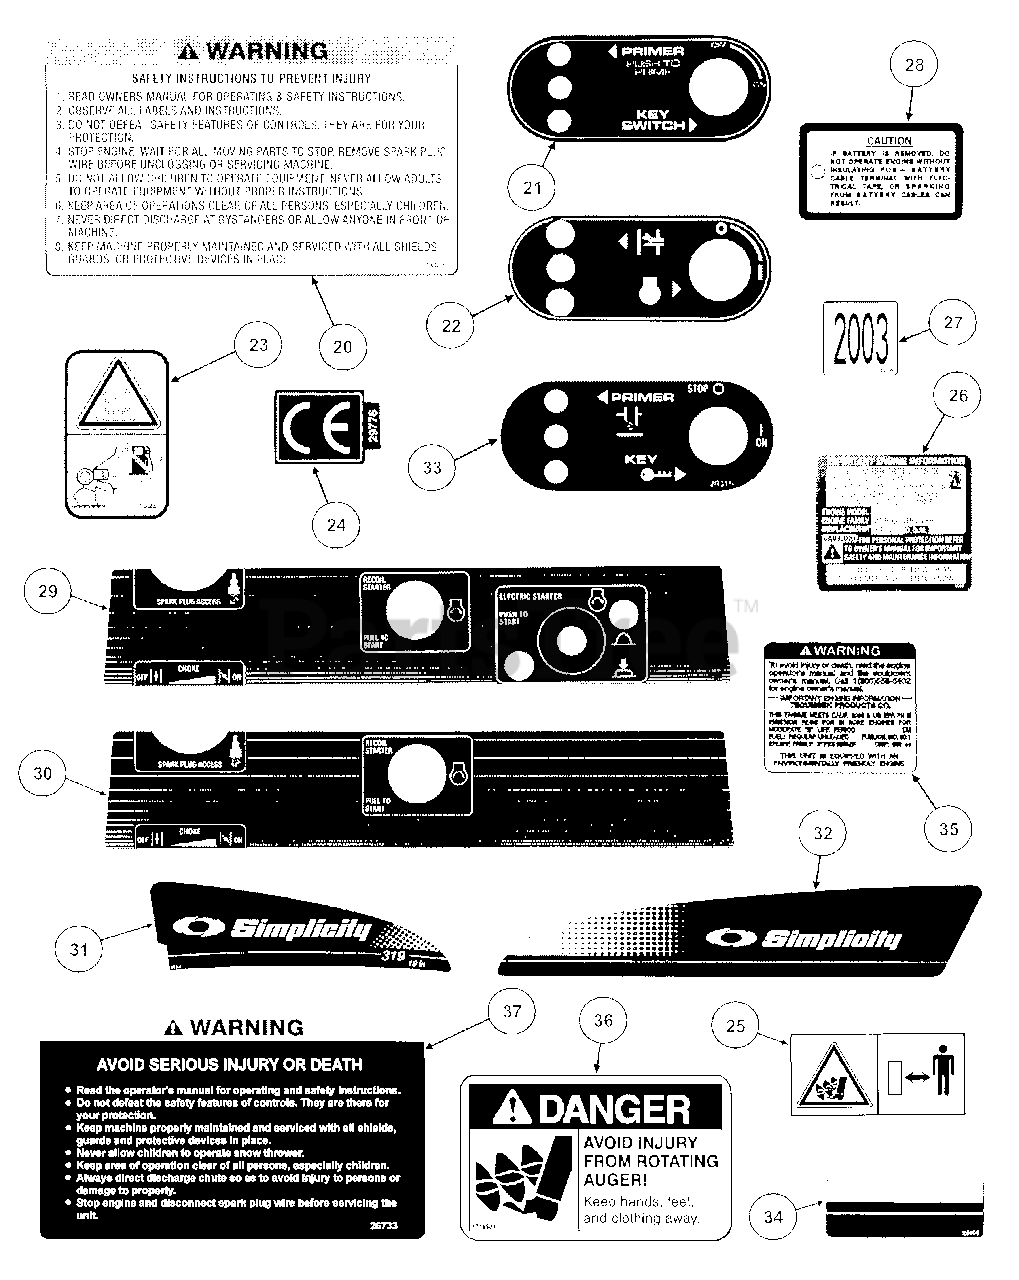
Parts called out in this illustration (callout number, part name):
20	DECAL, Warning Safety Instructions
21	DECAL, Primer Instruction
22	DECAL, Primer Instruction
23	DECAL, Fuel Safety
24	DECAL, Euro Community
25	DECAL, Foot/Danger
26	DECAL, Tecumseh 3HP Carb/EPA Certified
27	DECAL, 2003 Year of Manufacture
28	DECAL, Caution Tag
29	DECAL, Panel Instructions
30	DECAL, Panel Instructions
31	DECAL, Top Cover, Left Hand
32	DECAL, Top Cover, Right Hand
33	DECAL, Primer Instruction/Key Switch
34	DECAL, Top Cover, Front
35	DECAL, Tecumseh 3HP Carb/EPA Certified
36	DECAL, Danger, Auger
37	DECAL, Warning Safety Instructions
